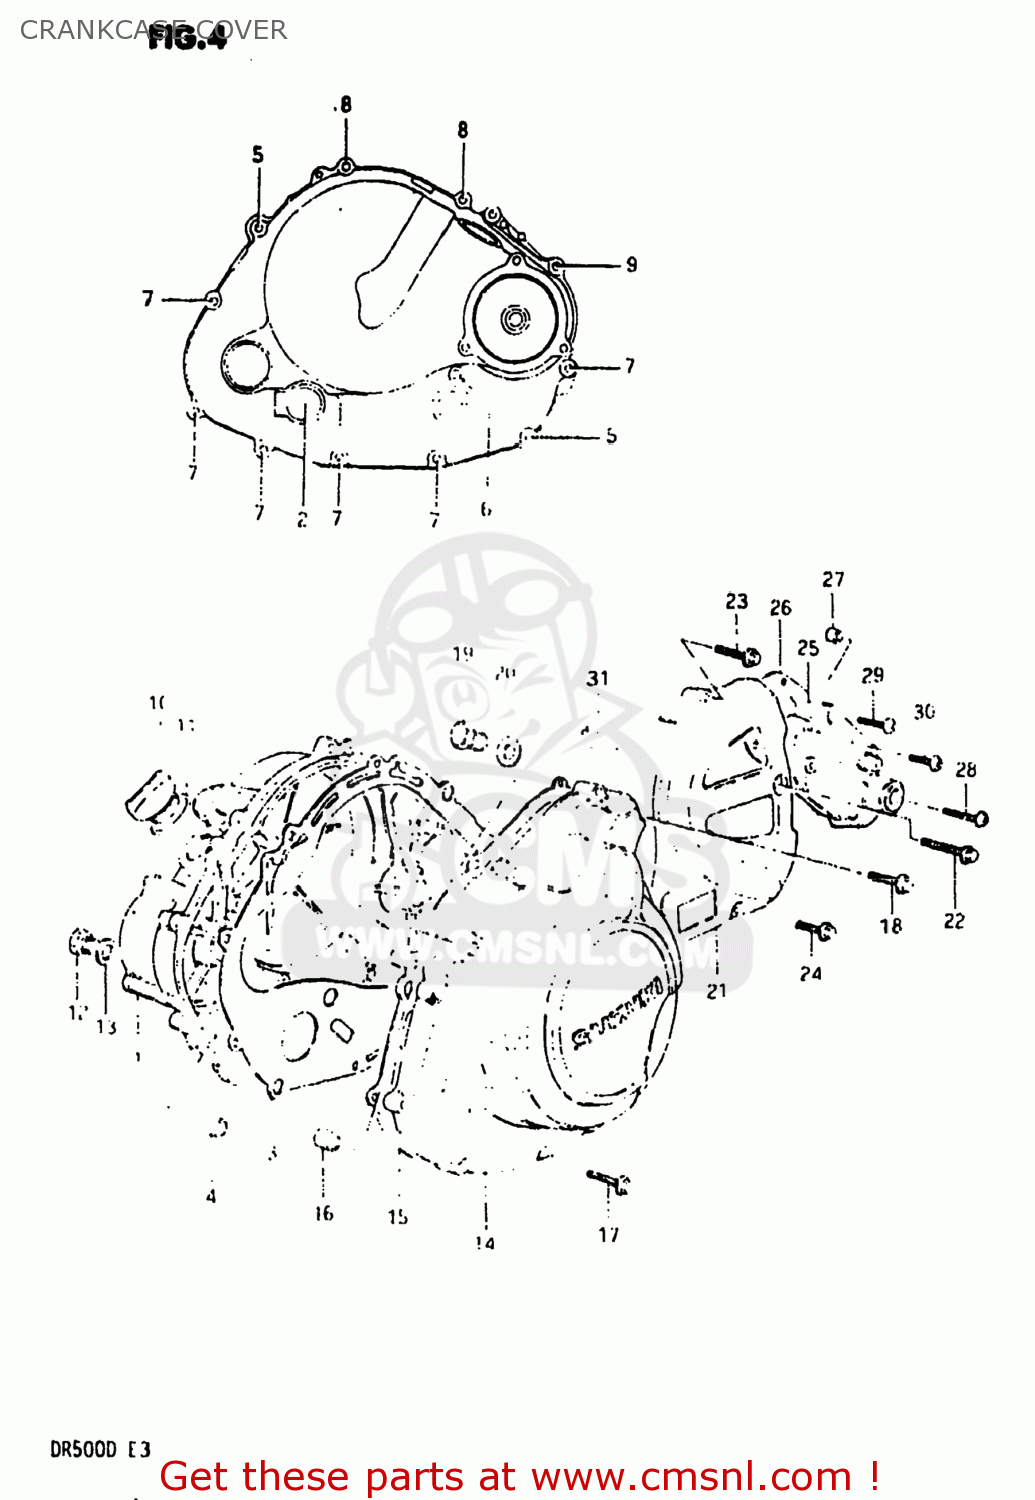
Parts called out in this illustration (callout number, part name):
1	COVER,CLUTCH
2	LENS,OIL LEVEL CHECK
3	GASKET,CLUTCH COVER (MCA)
4	PIN
5	BOLT 6X50
6	BOLT (6X40)
7	BOLT (6X35)
8	BOLT (6X25)
9	SCREW(6X25)
10	CAP
11	O RING(D:2.2,ID:32)
12	PLUG (14X12)
13	GASKET(14X19.2X2) (NAS)
14	COVER
15	GASKET,MAGNETO COVER (MCA)
16	PIN
17	BOLT (6*30)
18	BOLT (6X25)
19	PLUG(12X9)
20	GASKET(12.1X16.2X3.7) (NAS)
21	COVER,ENGINE SPROCKET
22	BOLT (6X45)
23	BOLT (6*30)
24	BOLT 6X20
25	COVER,GEAR SHIFT
26	CUSHION,ENGINE SPROCKET
27	PIN
28	SCREW (6X35)
29	SCREW 6X30
30	SCREW
31	PLUG
